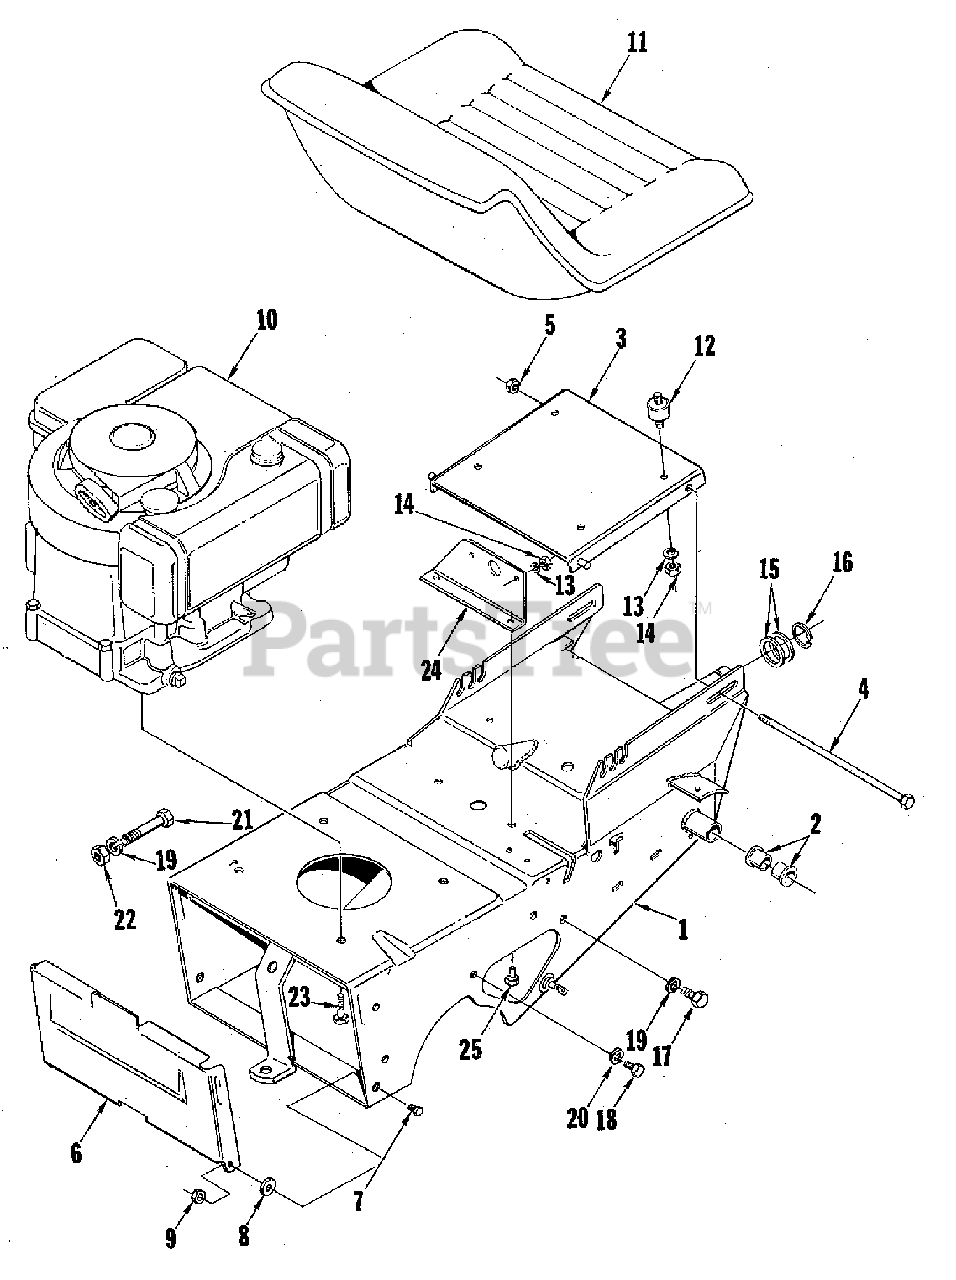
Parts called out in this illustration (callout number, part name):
1	REAR FRAME ASSEMBLY
4	SCREW, Special, 3/8-16 x 10
5	NUT, Lock, 3/8-26
7	SCREW, Hex, 1/4-20 x 5/8
8	WASHER, Nylon
9	NUT, Flange, 1/4-20
10	ENGINE
11	SEAT ASSEMBLY
13	WASHER, Lock, 5/16
14	NUT, Hex, 5/16-18
16	RING, Retaining
17	SCREW, Hex, 7/16-14 x 3/4
18	SCREW, Hex, 3/8-16 x 3/4
19	WASHER, Lock, 7/16
20	WASHER, Lock, 3/8
21	SCREW, Hex, 7/16-14 x 2-3/4
22	NUT, Hex, 7/16-14
23	SCREW, Special, 3/8-16 x 1-1/4
24	PLATE, Engine
25	SCREW, Hex, Cap, 3/8-16 x 1/2
